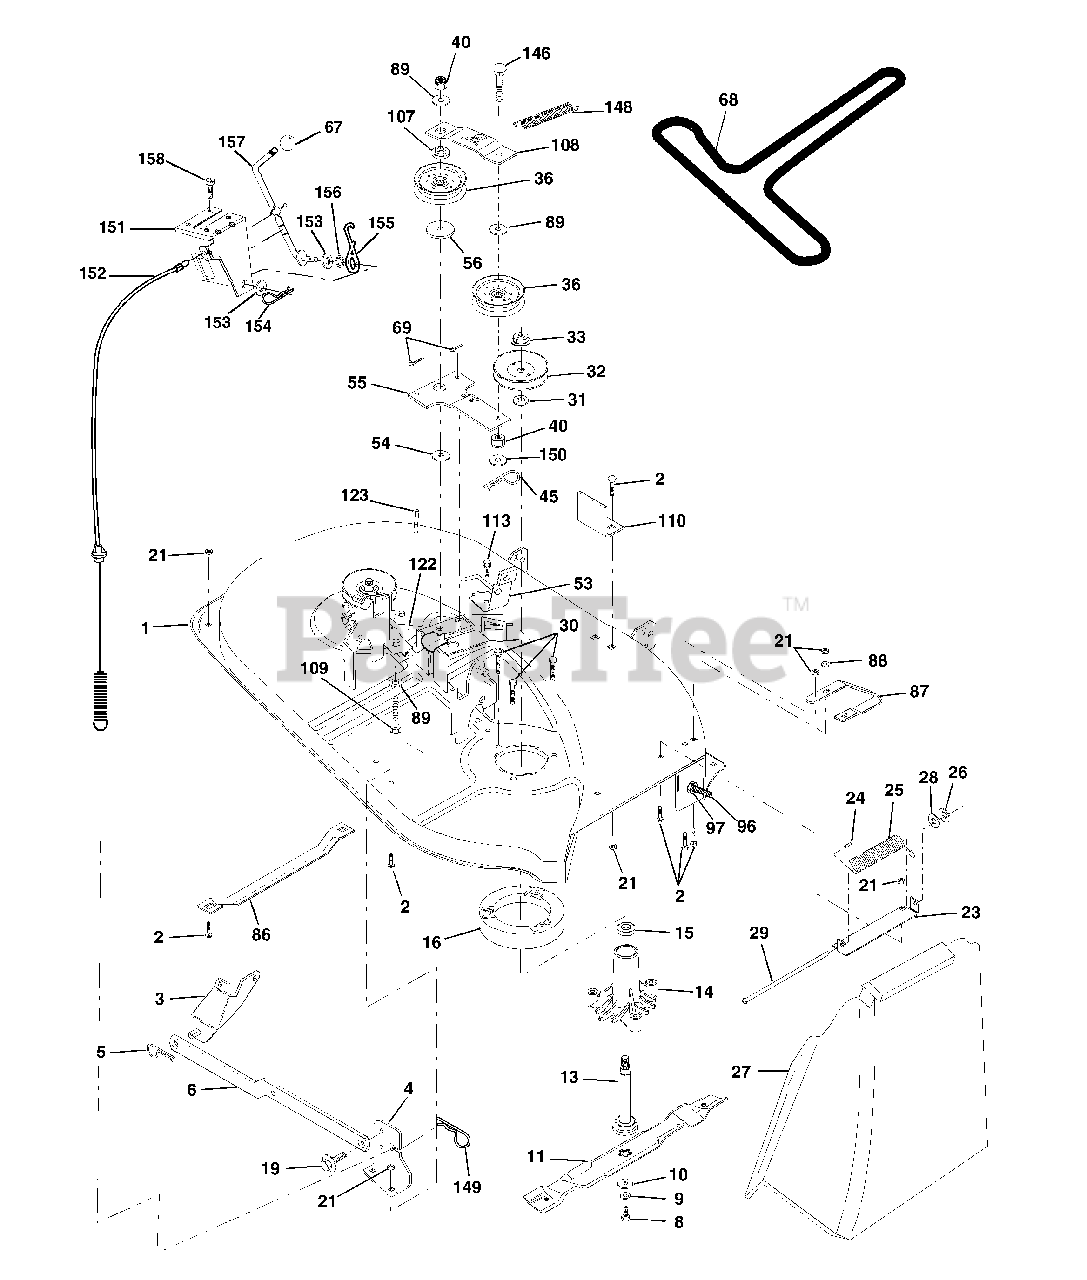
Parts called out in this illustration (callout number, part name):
1	Mower Housing Assembly
2	Bolt Carriage 5/16-18 x 3/4
3	Bracket Asm Fr. Sway Bar
4	Bracket Deck Sway Bar 38"/42"
5	Retainer Spring
6	Bar Sway Deck
8	Bolt 3/8-24 x 1.25 Grade 8
9	Washer, Lock 3/8
10	Washer, Hardened
11	Blade Mower
13	Shaft Assembly, Mandrel, Vented
14	Housing, Mandrel, Vented
15	Bearing, Ball, Mandrel
16	Stripper, Vented Mower Deck
19	Bolt, Shoulder
21	Nut
23	Bracket, Mower Deflector
24	Cap, Sleeve
25	Spring, Torsion, Deflector
26	Nut, Push
27	Shield, Deflector
28	Washer 11/32 x 5/8 x 16 Gauge
29	Rod, Hinge
30	Screw Thdrol.
31	Washer, Spacer
32	Pulley, Mandrel
33	Nut, Toplock
36	Pulley, Idler, Flat
40	Nut, Crownlock 3/8-16 Unc
45	Retainer
53	Brake Assembly
54	Washer, Hardened
55	Idler Arm Assembly
56	Spacer, Retainer
67	Knob
68	V-Belt, 42" Mower
69	Pin, Cotter 3/32 x 3/4
86	Runner, LH
87	Runner, RH
88	Washer 11/32 x 3/4 x 16 Ga
89	Washer 13/32 x 1 x 12 Ga.
107	Spacer Retainer
108	Stiffener, Idler Arm
109	Bolt, Hex Hd 3/8-16 x 2-1/2
110	Upstop Deck Front 38"
113	Screw 5/16-1/ x 3/4
122	Rod, Brake LH
123	Rod, Brake RH
146	Bolt Carriage Idler
148	Spring Return Idler
149	Retainer Spring Yellow
150	Washer 9/32 x 3/4 x 16 Ga.
151	Bracket Clutch Cable
152	Clutch Cable 38"/46"
153	Washer Flat 3/8" Type B
154	Spring Retainer
155	Spring Retention LVR CLTCH CAB
156	Spacer Clutch Cable
157	Rod Clutch Cable 3/8"
158	Screw Hex Thd Cut 1/4-20 x 1/2
